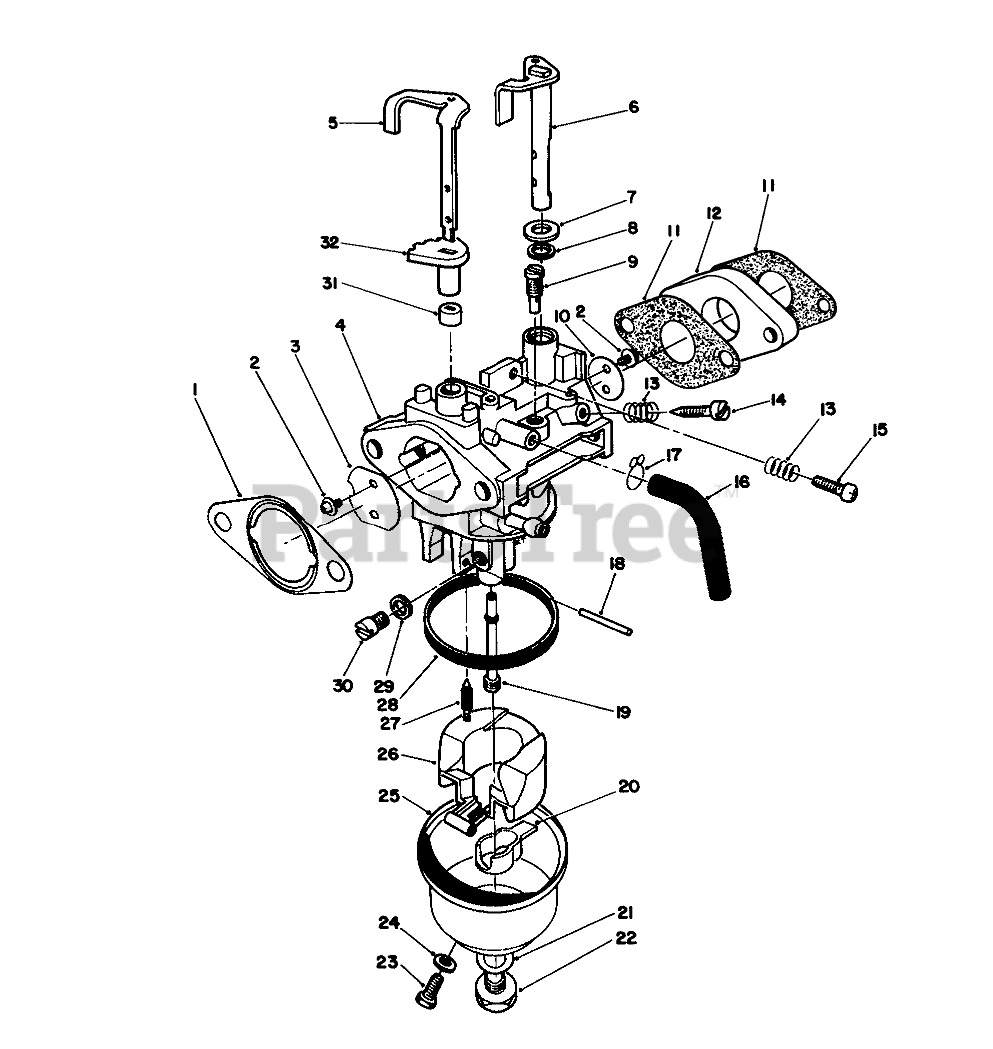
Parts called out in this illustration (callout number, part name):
1	GASKET F/W ENGINE
2	Screw
3	VALVE
4	Body-Carburetor
5	Shaft-Choke Valve
6	SHAFT
7	WASHER
8	Seal-Throttle Shaft
9	PILOT JET
10	VALVE
11	Gasket-Carburetor
12	CARB INSULATOR
13	SPRING-PILOT SCREW
14	ADJUSTER
15	SCREW
17	CLAMP
18	Pin
19	NOZZLE
20	SPACER
21	GASKET
22	SCREW
23	SCREW
24	GASKET
26	FLOAT
27	NEEDLE
28	FLOAT BOWL GASKET
29	SPACER
30	MAIN JET
31	LOWER CHOKE RING
32	UPPER CHOKE RING
